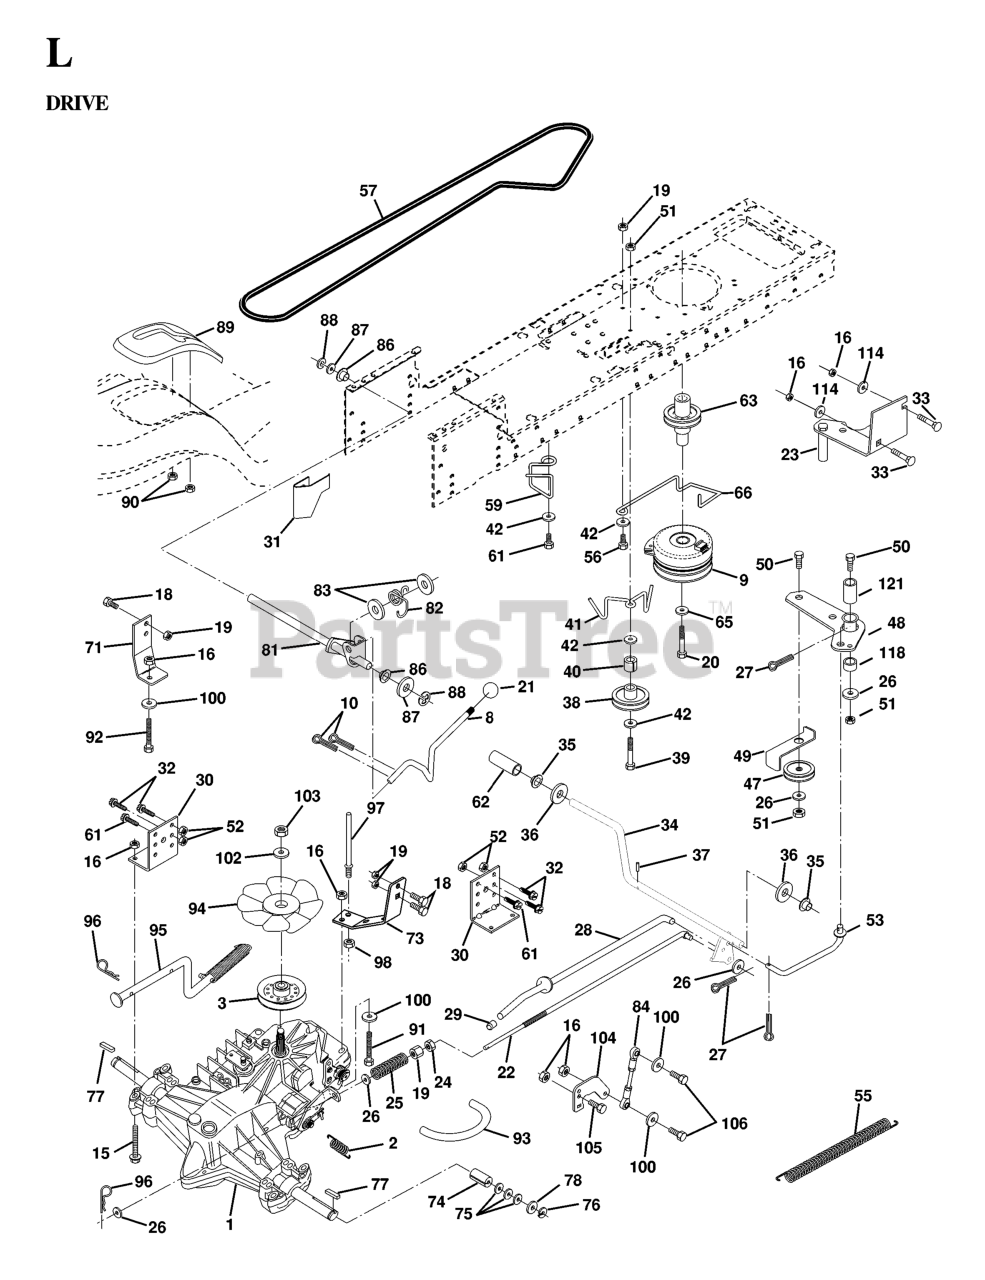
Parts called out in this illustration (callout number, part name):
2	SPRING BRAKE
3	PULLEY, TRANSAXLE
8	ROD SHIFT FENDER
9	CLUTCH.ELECT.EVX.
10	PIN COTTER
15	BOLT HEX 5/16-18 GR 5
16	NUT.71038.31-18.HEX.NYLOCK
19	NUT
20	BOLT HEX
21	KNOB.DUCKHEAD.1/2
22	ROD BRAKE HYDRO
23	BRACKET, ASM CLUTCH MTG
24	NUT
25	SPRING ROD LT
26	WASHER
27	COTTER PIN
28	ROD BRAKE PARK LT
29	PLUNGER CAP
30	BRACKET TRANSAXLE
31	KEEPER BELT LH
32	BOLT
33	RP BOLT 5/16-18 X3/4 ZN/YEL GR
34	SHAFT, FOOT PEDAL
35	BEARING.NYLON
37	DRIVE PIN
38	PULLEY.IDLER.FLAT
41	KEEPER, BELT IDLER
42	WASHER
47	IDLER PULLEY
48	BELLCRANK ASSEMBLY
49	RETAIN BELT
50	BOLT
52	LOCKNUT
53	LINK, CLUTCH LT
55	SPRING, RETURN LT
57	BELT
59	KEEPER CENTER SPAN
61	SCREW
62	COVER, PEDAL (1 2)
63	PULLEY, CLUTCH ELECT EVX
65	LOCKWASHER
66	KEEPER BELT ENGINE
71	STRAP LH TORQUE
73	STRAP TORQUE RH HYDRO
74	SPACER SPLIT
77	SQUARE KEY
81	SHAFT ASSY
82	SPRING,TORSION
83	WASHER
84	ROD.TIE.BALL.4.75
86	BUSHING.STEERING.ROD LTB-WSL
89	CONSOLE SHIFT
90	NUT.PUSH.3/16
91	BOLT.FIN HEX 5/16-18UNC X2 1/4
92	HEX BOLT
93	LINE FUEL HYD 4"
94	FAN 7" HYDRO
95	CONTROL ARM, BYPASS HYDRO
96	RETAINER M
97	KEEPER BELT RH
100	WASHER M
103	NUT.HEX.1/2-20
104	CONTROL ARM
106	BOLT.5/16-18X1-1/4 FULL.THREAD
114	Washer 11/32 x 3/4 x 14 Gauge
118	SPACER BELLCRANK
121	NYLINER CLUTCHING
